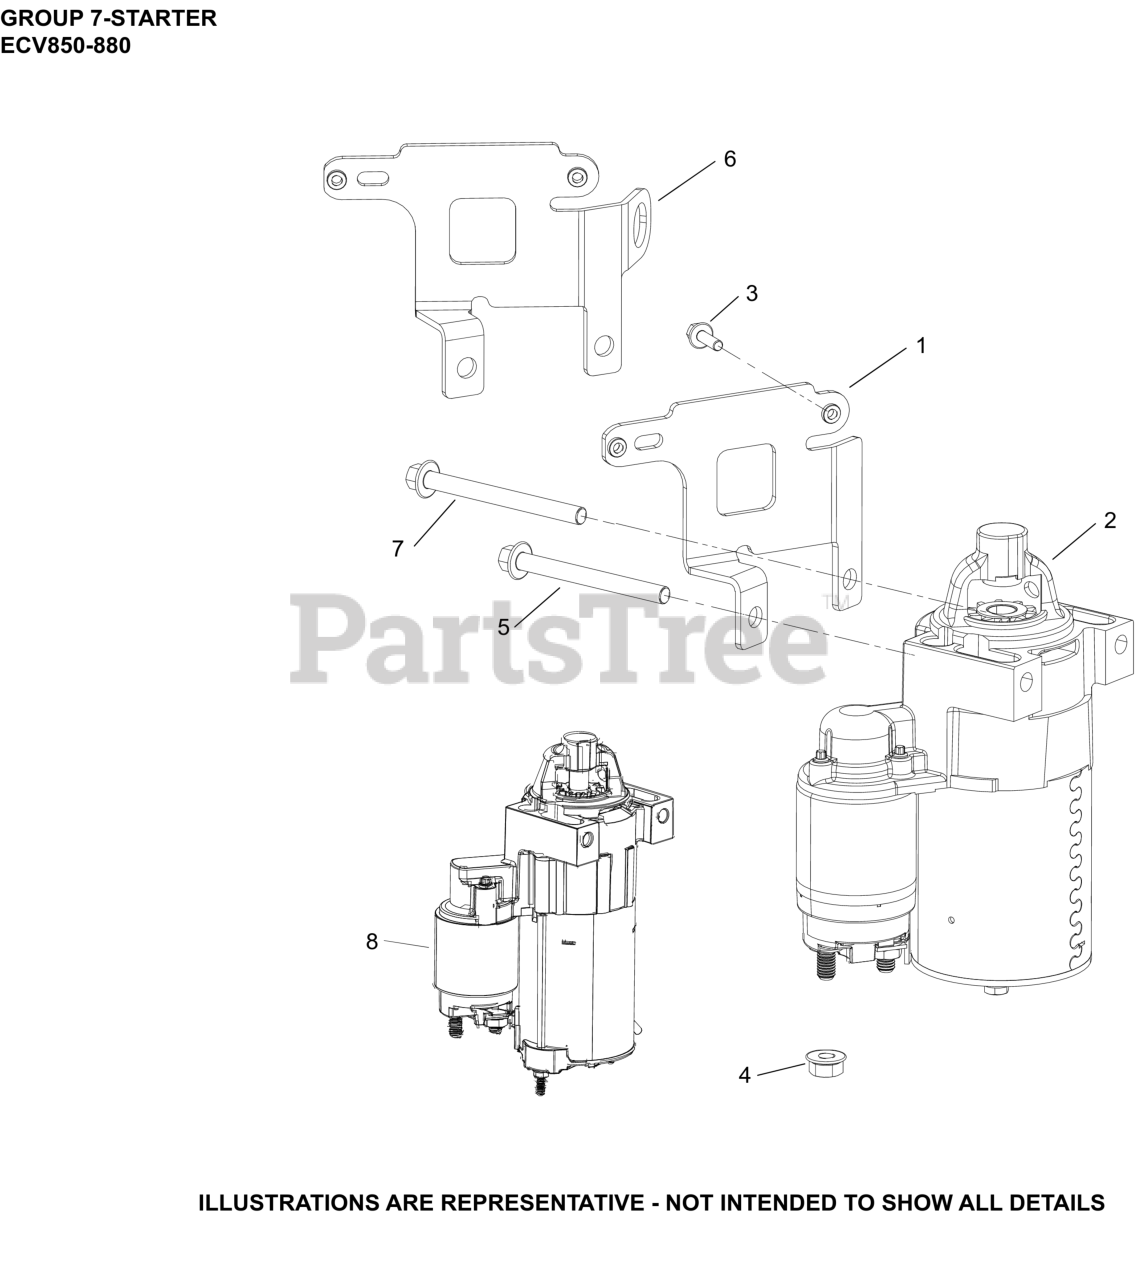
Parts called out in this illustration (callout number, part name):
1	BRACKET, ECU
2	STARTER, SOLENOID SHIFT
3	SCREW, HVY FLG M5X.8X16
4	NUT, FLG M8X1.25
5	SCREW, FLG M8X1.25X80
